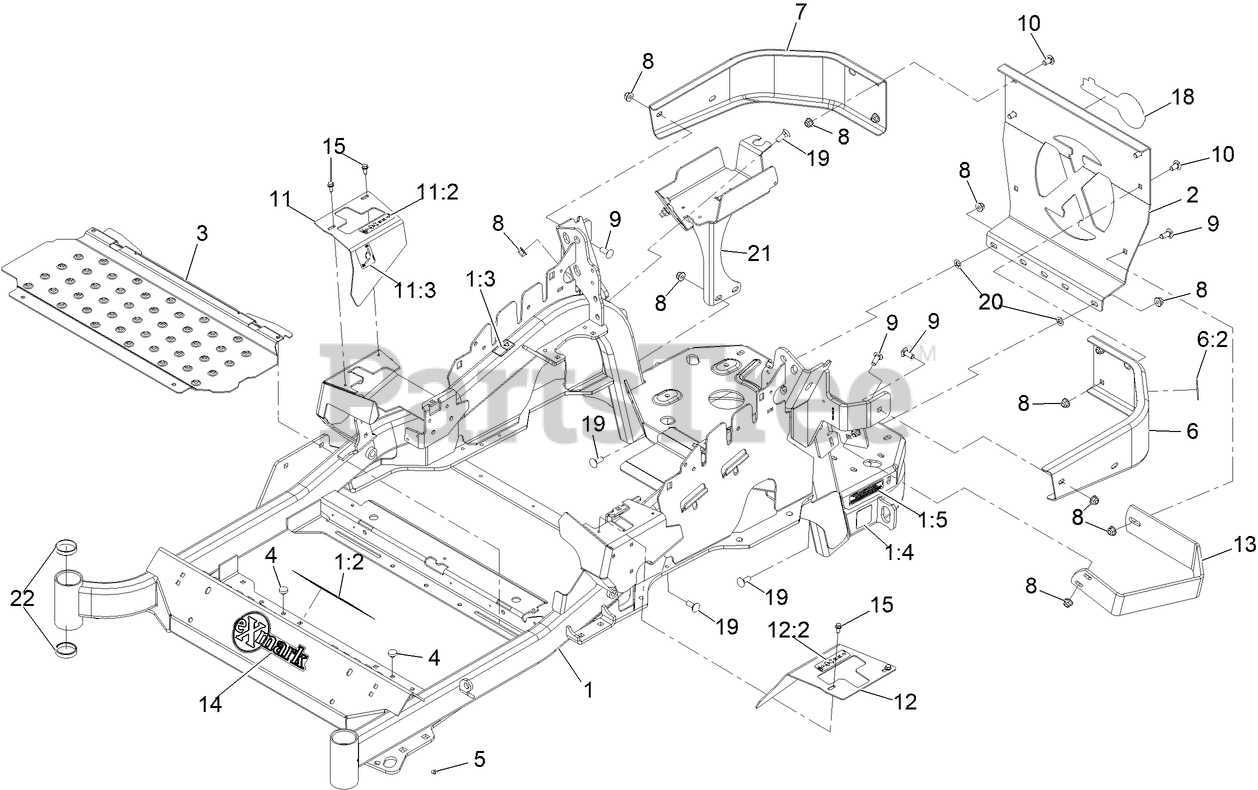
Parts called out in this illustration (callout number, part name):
1	Mainframe ASM-52 W/Decals
1:2	DECAL-ARRESTOR, SPARK
1:3	DECAL-WARNING
1:4	DECAL-HAZARD, PINCHED FINGER
1:5	DECAL-DANGER
2	PLATE,REAR GUARD
6	LH BUMPER ASM
6:2	DECAL-WARNING
7	BUMPER-RH
8	NUT-HF, NI
9	SCREW-CARR
10	SCREW-CARR
11	RH MOTION CONTROL COVER ASM
11:2	DECAL-CONTROL, MOTION
11:3	DECAL-PARK BRAKE, CE
12	LH MOTION CONTROL COVER ASM
12:2	DECAL-CONTROL, MOTION
13	GUARD-MUFFLER
14	DECAL-EXMARK
15	SCREW-HWH
18	DECAL, EXMARK LOGO
19	BOLT-CARR
20	NUT-PUSH
21	Weld-Battery Mount
22	CUP-BEARING
